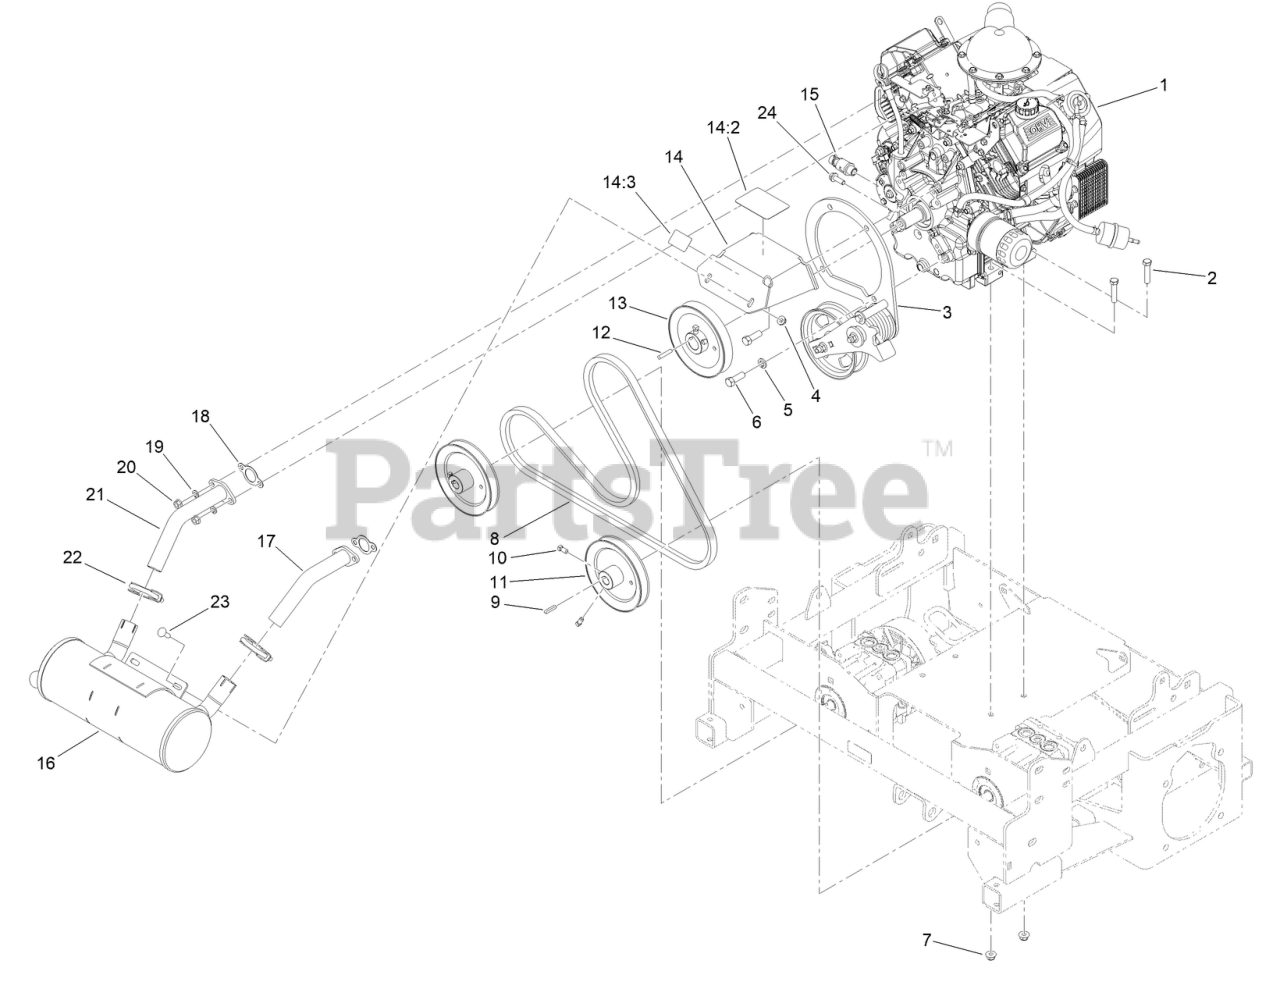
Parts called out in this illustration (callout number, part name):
1	ENGINE-KOHLER, CH740-3136
2	SCREW-HH
3	TENSIONER ASM
5	WASHER-LOCK
6	SCREW-HH
7	NUT-HF, NI
9	KEY, 5MM X 5MM X 29MM
10	SCREW-SET
11	PULLEY-DRIVEN
12	KEY-SQUARE
13	PULLEY, DRIVE
14	MUFFLER BRACKET ASM W/DECALS
14:2	DECAL-BELT ROUTING
14:3	DECAL-WARNING
15	VALVE-DRAIN, OIL
16	MUFFLER
17	HEADER-MUFFLER, LH
18	GASKET-EXHAUST
19	WASHER-LOCK
21	HEADER-MUFFLER, RH
22	Clamp-Muffler
23	SCREW-HHF
24	SCREW-HH
